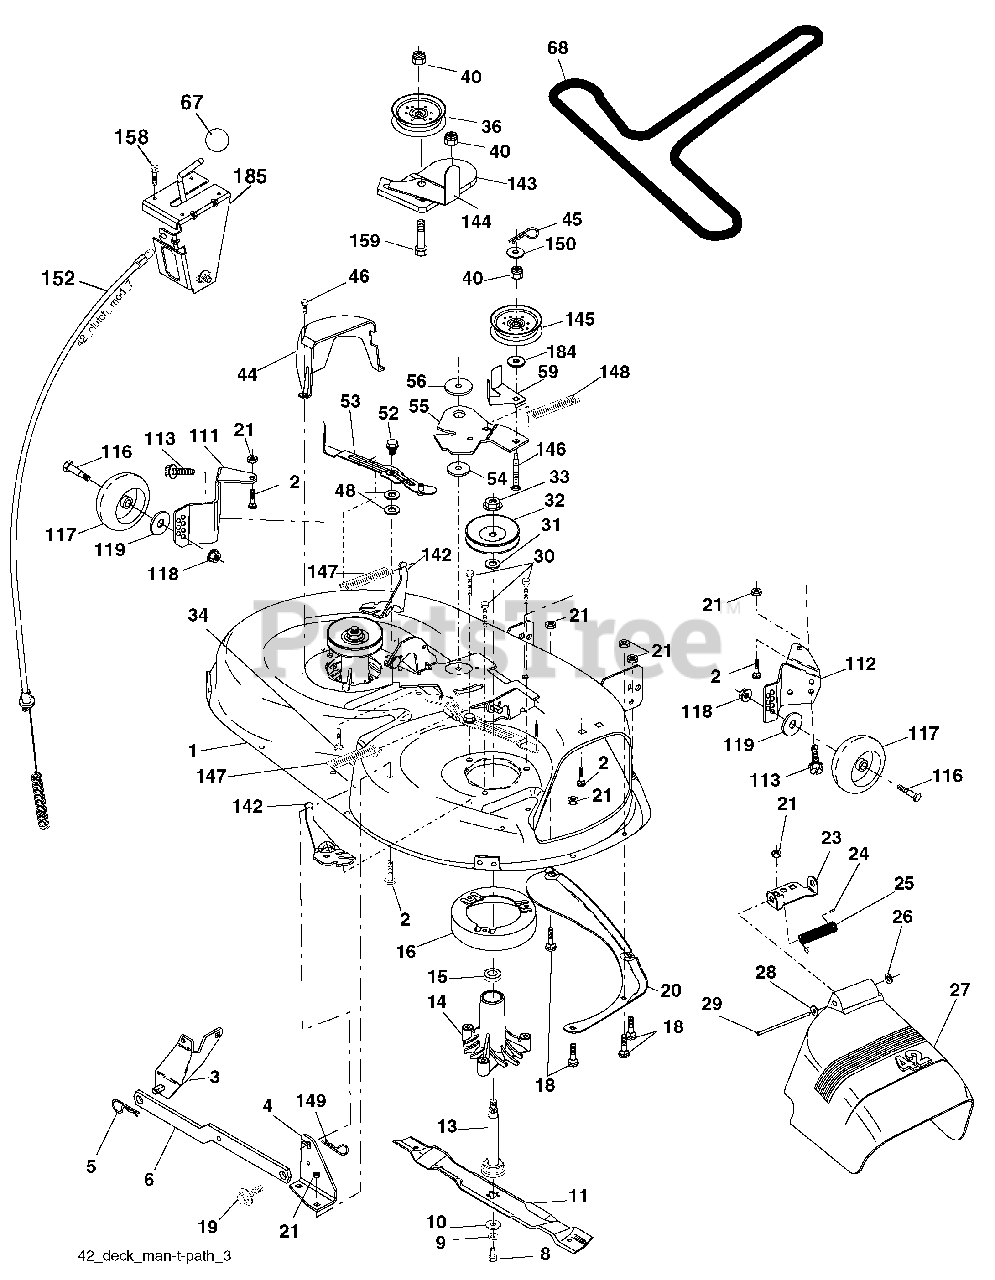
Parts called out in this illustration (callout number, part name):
1	Mower Deck Assembly, 42"
2	Bolt
3	Bracket Asm Fr. Sway Bar 3/42
4	Bracket Asm Deck 42" Sway Bar
5	Retainer Spring
6	Bar Sway Deck
8	Bolt 3/8-24 x 1.25 Gr. 8 patched
9	Washer, Lock
10	Washer, Hardened (The following Blades are available)
11	Blade Mower 42” Hi-Lift (for bagging and discharging)
11	Blade, Mulching 42” Std (for mulching mowers only)
11	Blade Mulching 42” Premium (For better wear when mulching)
13	Shaft As sem bly, Mandrel, Vented
14	Housing, Mandrel, Vented
15	Bearing, Ball, Mandrel
16	Stripper, Mandrel Deck
18	Bolt, Carriage 5/16-18 x 5/8
19	Bolt, Shoulder
20	Baffle, Vortex
21	Nut
23	Bracket, Deflector Mower 42"
24	Cap, Sleeve 80 x 112 Blk Mower
25	Spring, Torsion, Deflector 2 52
26	Nut, Push Phos & Oil
27	Shield, Deflector 42" Blk
28	Washer 11/32 x 5/8 x 16 Ga.
29	Rod, Hinge 42" 6 75 W/G
30	Screw Thdrol
31	Washer, Spacer Mower Vented
32	Pulley, Mandrel
33	Nut, Toplock
34	Bolt Carr SH 3/8-16 x 1-1/2 Gr.5
36	Pulley, Idler, Flat
40	Nut Lock 3/8-16
44	Guard, Mandrel, LH
45	Retainer
46	Screw, Thdrol 1/4-20 x 5/8 T
48	Washer, Hardened
52	Bolt, Shoulder 5/16-18 unc
53	Arm Assembly, Pad, Brake
54	Washer, Hardened
55	Arm, Idler
56	Spacer, Retainer
59	Guard TUV Idler
67	Knob Round
68	V-Belt, 42" Mower
111	Bracket Asm. Whl Ga. LH
112	Bracket Asm Whl Ga. RH
113	Screw 5/16-18
116	Bolt, Shoulder
117	Wheel, Gauge
118	Nut Centerlock 3/8-16
119	Washer 3/8 x 7/8 x 14 Ga.
142	Arm Spring Brake Mower
143	Bracket Arm Idler 42"
144	Keeper Belt 42" Clutch Cable
145	Pulley Idler Flat
146	Bolt Carriage Idler
147	Spring Extension
148	Spring Return Idler
149	Retainer Spring Yellow
150	Washer 9/32 x 3/4 x 10 Ga.
152	Clutch Cable 42"
158	Screw Hex Thd Cut 1/4-20 x 1/2
159	Bolt Rdhd Sqn 3/8-16 unc x 1-3/4
184	Washer 13/32 x 7/8 x 10 Ga.
185	Head Asm Cable Clutch
185	Mandrel Assembly
185	Replacement Mower, Complete
